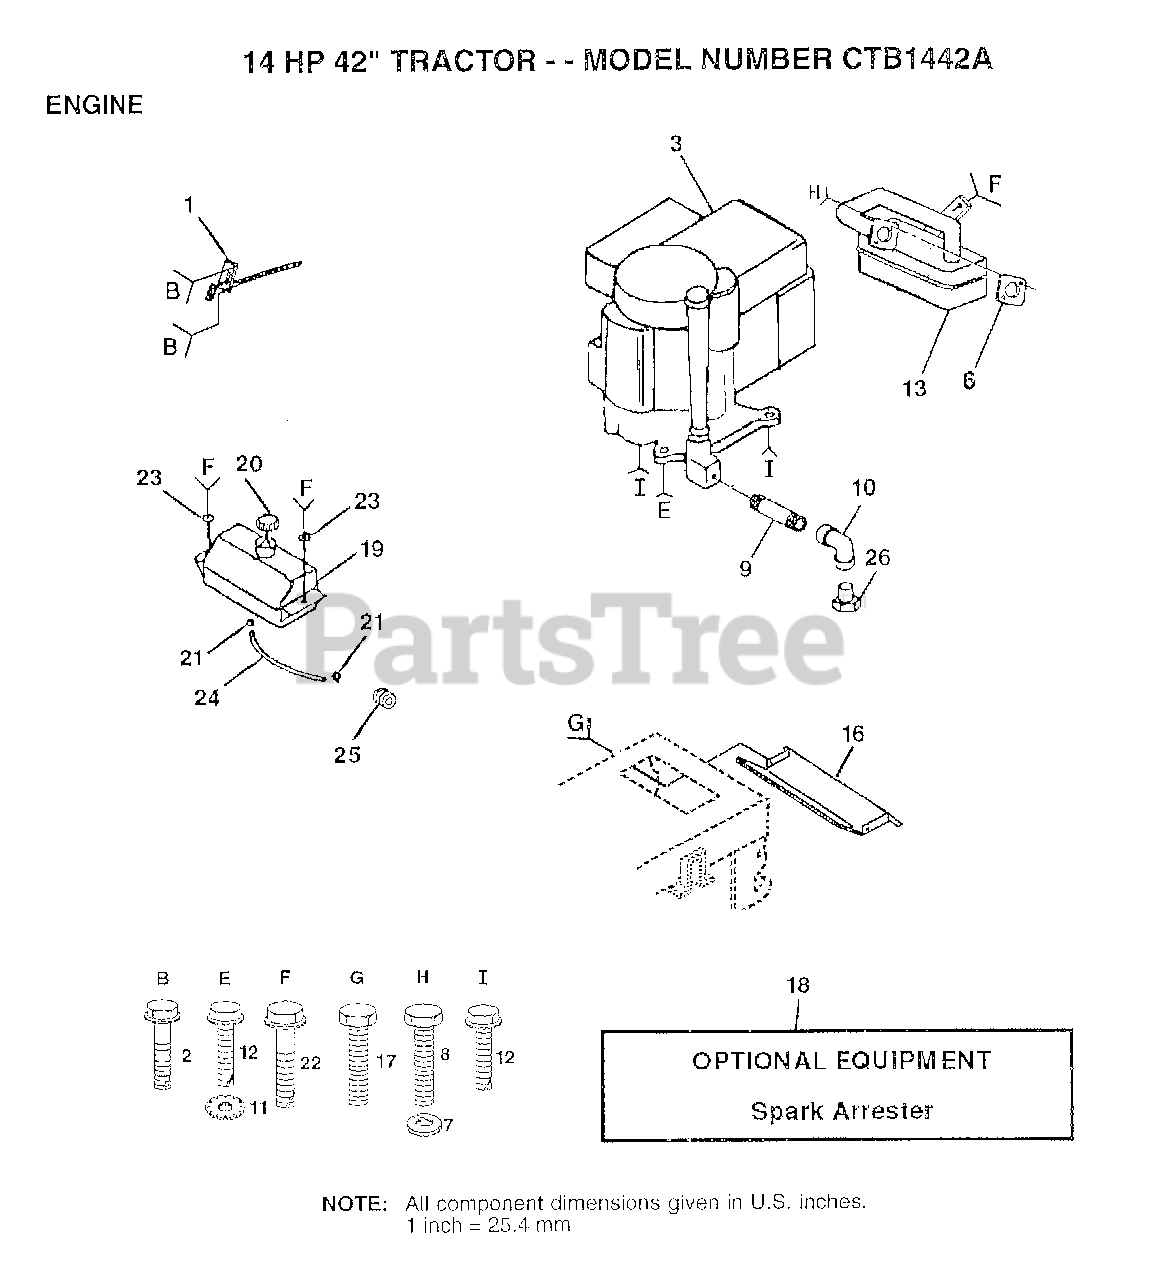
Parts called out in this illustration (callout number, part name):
1	THROTTLE CONTROL
2	SCREW LT
7	LOCKWASHER
8	SCREW
9	PIPE NIPPLE
10	ELBOW
11	LOCKWASHER
12	SCREW
13	MUFFLER
16	HEAT SHIELD
17	SCREW
19	TANK.FUEL.LT.
21	HOSE CLAMP
22	SCREW HEX CRT
23	WASHER
24	FUEL LINE T
